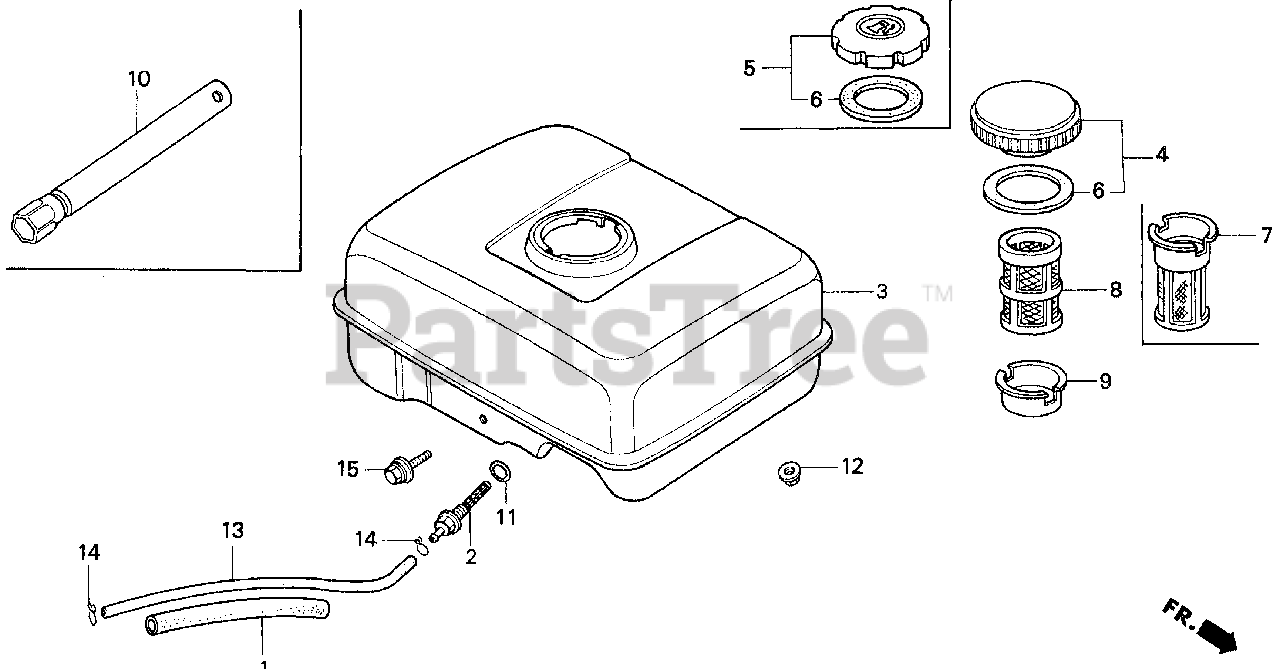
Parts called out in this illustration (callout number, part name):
1	RUBBER, SUPPORTER (107MM)
2	JOINT, FUEL TANK
3	TANK, FUEL *NH31* (MCKINLEY WHITE)
3	TANK, FUEL *NH1* (BLACK)
4	CAP, FUEL FILLER
5	CAP, FUEL FILLER
6	GASKET, FUEL FILLER CAP
11	O-RING (13.5X1.5) (ARAI)
12	NUT, FLANGE (6MM)
13	BULK HOSE, FUEL (4.5X3000) (4.5X140)
14	CLIP, TUBE (B8)
15	BOLT, FLANGE (6X29)
15	BOLT, FLANGE (6X25)
